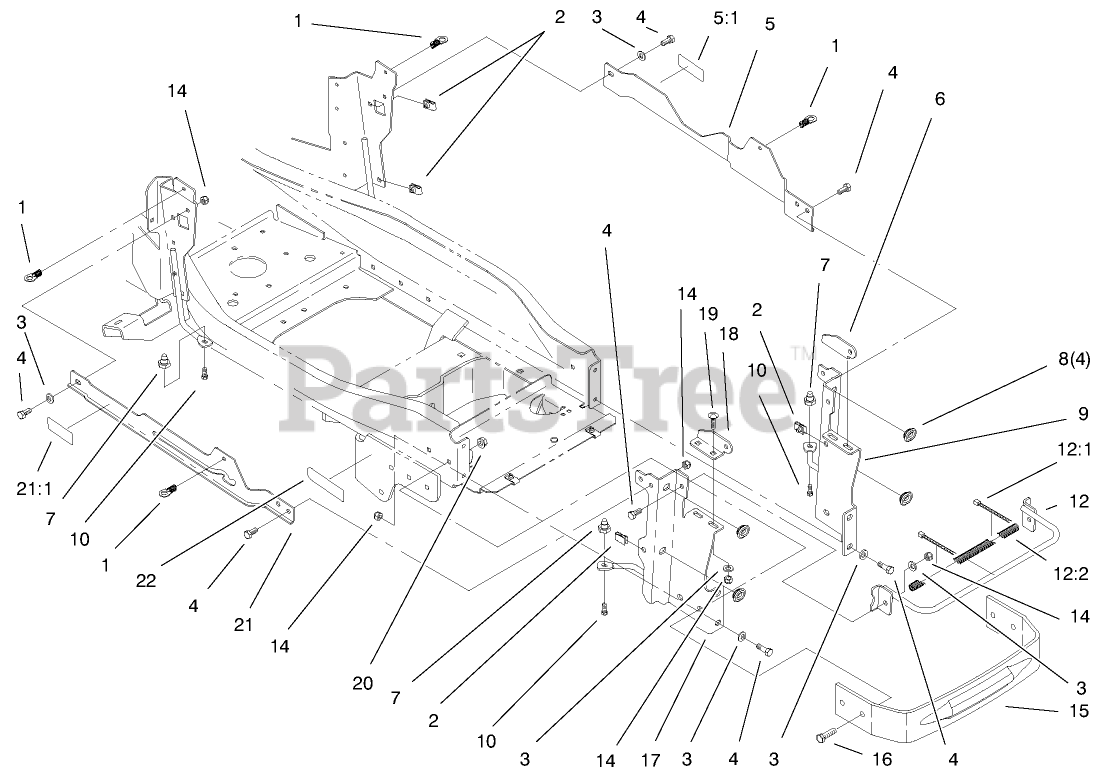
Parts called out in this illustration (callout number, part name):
1	LATCH ASM
3	WASHER-PLAIN
4	SCREW-HH
5:1	DECAL-WARNING
6	BRKT-LOWER HINGE LH
7	MOUNT-SIDEPANEL
8	GROMMET
10	SCREW-PLASTITE
12	ASSEMBLY - HOOD SUPPORT
12:1	COVER-BRACE
12:2	TIE-CABLE
14	NUT-LOCK, NI
16	SCREW-HH
17	SUPPORT-HOOD, RH
18	BRACKET-LOWER HINGE RH
19	SCREW-CARR
20	NUT-LOCK, NI
21:1	DECAL-WARNING
22	DECAL-ATTACH A-MATIC
